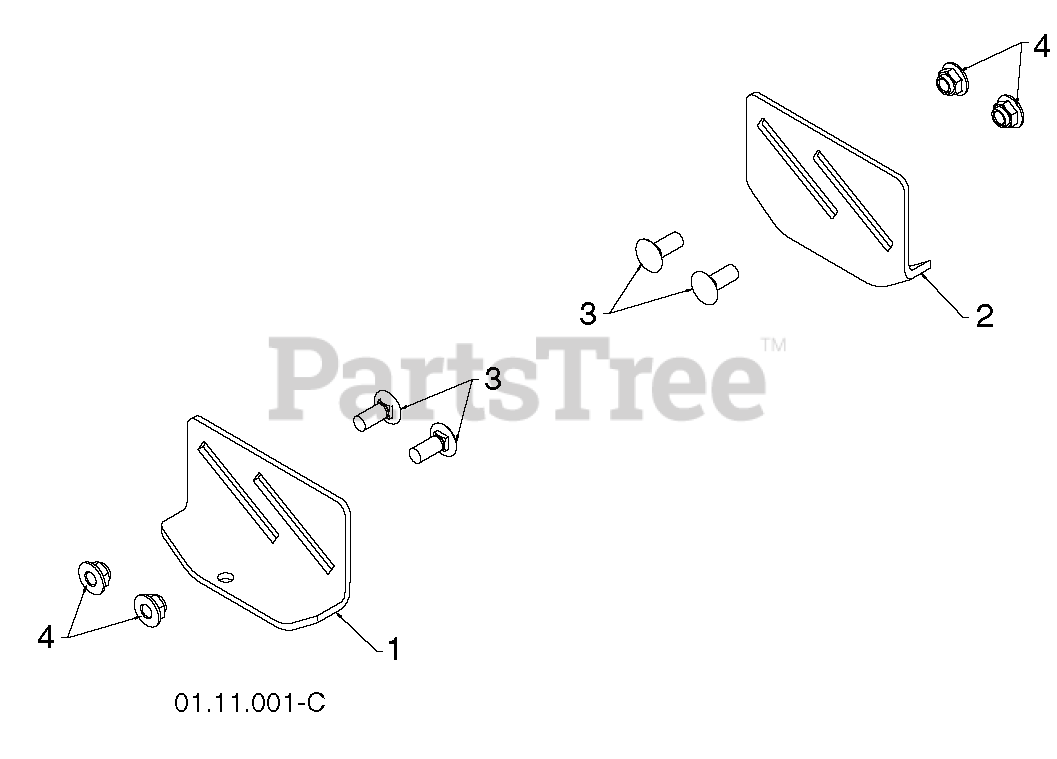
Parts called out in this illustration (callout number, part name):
1	SKID PLATE LH
2	SKID PLATE RH
4	NUTNYLOK.FLRANGE.5/16-18
